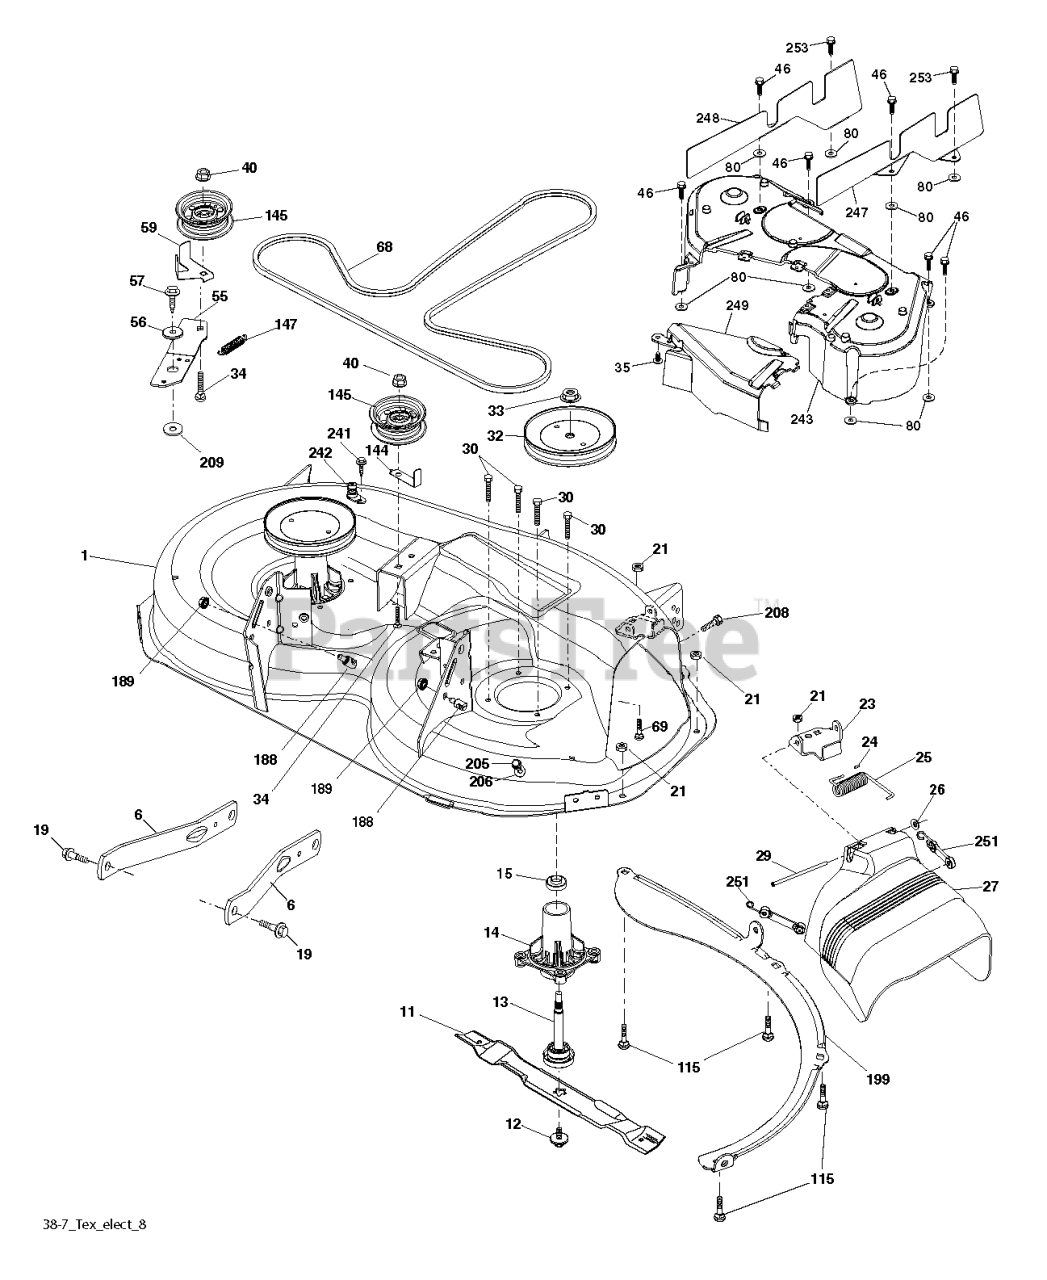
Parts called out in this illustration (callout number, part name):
1	DECK.WELD.38.NGW.TX.W/HOL.GREY
6	ARM.SUSPENSION.MOWER.R
8	BOLT.WASHER.ASM.7/16-2
11	BLADE 38" PREMIUM
13	SHAFT.ASM.MDRL.N/GREASE.38
14	RP.HOUSING.MANDREL.4PT.
19	BOLT.SHOULDER
21	LOCKNUT
23	BRKT.DEFLECTOR.38"2005+
24	CAP-SLEEVE LT
25	SPRING.TORSION.DEFLECT
26	NUT PUSH M
27	SHIELD ASM.DFLCTR MWR.38-7"BLK
29	ROD.HINGE
30	SCREW, WASHER HEAD
31	WASHER.SPACER.MANDREL
32	PULLEY MANDREL
33	NUT.FLANGE.LOCK.TOP
34	BOLT.3/8-16X1.50
35	FASTENER.XMAS.TREE
40	NUT LOCK FLG 3/8-16 UNC
46	SCREW.1/4-20X5/8
55	IDLER.ARM
56	SPACER.RETAINER
57	SCREW 3/8-16X1
59	GUARD, BELT
68	BELT BELT 38' ELEC. DECK
69	BOLT
80	PALNUT 1/4
115	BOLT.CARR.5/16-18X5/8.SHORT
144	KEEPER BELT
145	PULLEY.IDLER.48"PRIMARY
147	SPRING.MOWER.DRIVE.ELECTRIC
188	STUD.FASTNER.W/ANTI-ROTATE
189	NUT LOCK HEX FLANGE 5/16-18
199	BAFFLE.VORTEX.FRONT.38"
205	SCREW
206	WASHER
208	SCREW 3/8-16X1/2
209	WASHER 12/32X2X10GA
241	SCREW.TT.#10-32X.5.3/8.FLANGE
242	PORT.WASHOUT
243	COVER DECK 38-7
247	SHIELD RIGHT
248	SHIELD LEFT
249	COVER CABLE CLUTCH
251	ELASTIC STRAP KIT
253	SCREW
